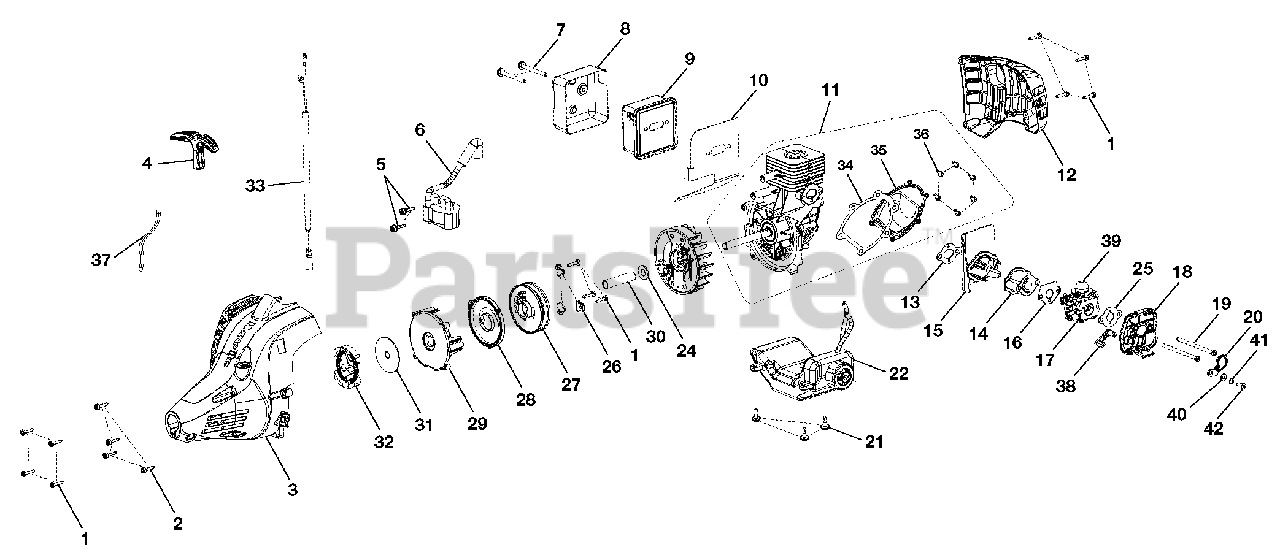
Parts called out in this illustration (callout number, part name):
1	Screw (M4 x 18 mm)
2	Screw (M4 x 16 mm)
3	Front Housing Assembly
4	Pulley Handle
5	Screw (M4 x 19 mm)
6	Ignition Module
7	Screw (10-24 x 2-3/16 in.)
8	Heat Shield
9	Muffler Assembly
10	Muffler Gasket
11	Short Block Assembly
12	Rear Housing
13	Intake Gasket
15	Heat Dam Deflector
16	Carburetor Gasket
17	Carburetor
18	Air Box Base
19	Screw (M5 x 79 mm)
20	Choke Plate
21	Screw (M4 x 10 mm Shoulder)
22	Fuel Tank Assembly w/Cap
23	Flywheel Assembly
24	Washer
25	Carburetor Gasket
26	Pulley Retainer
27	Starter Pulley Assembly
28	Spring & Container Assembly
29	Starter Housing
30	Spacer Tube
31	Clutch Washer
32	Clutch Assembly
33	Lead Assembly
34	Gasket
35	Crankcase Cover
36	Screw (M4 x 12 mm)
37	Starter Rope (42 in.)
38	Choke Lever
39	Primer Bulb
41	Curved Washer
42	Screw (M4 x 12 mm)
